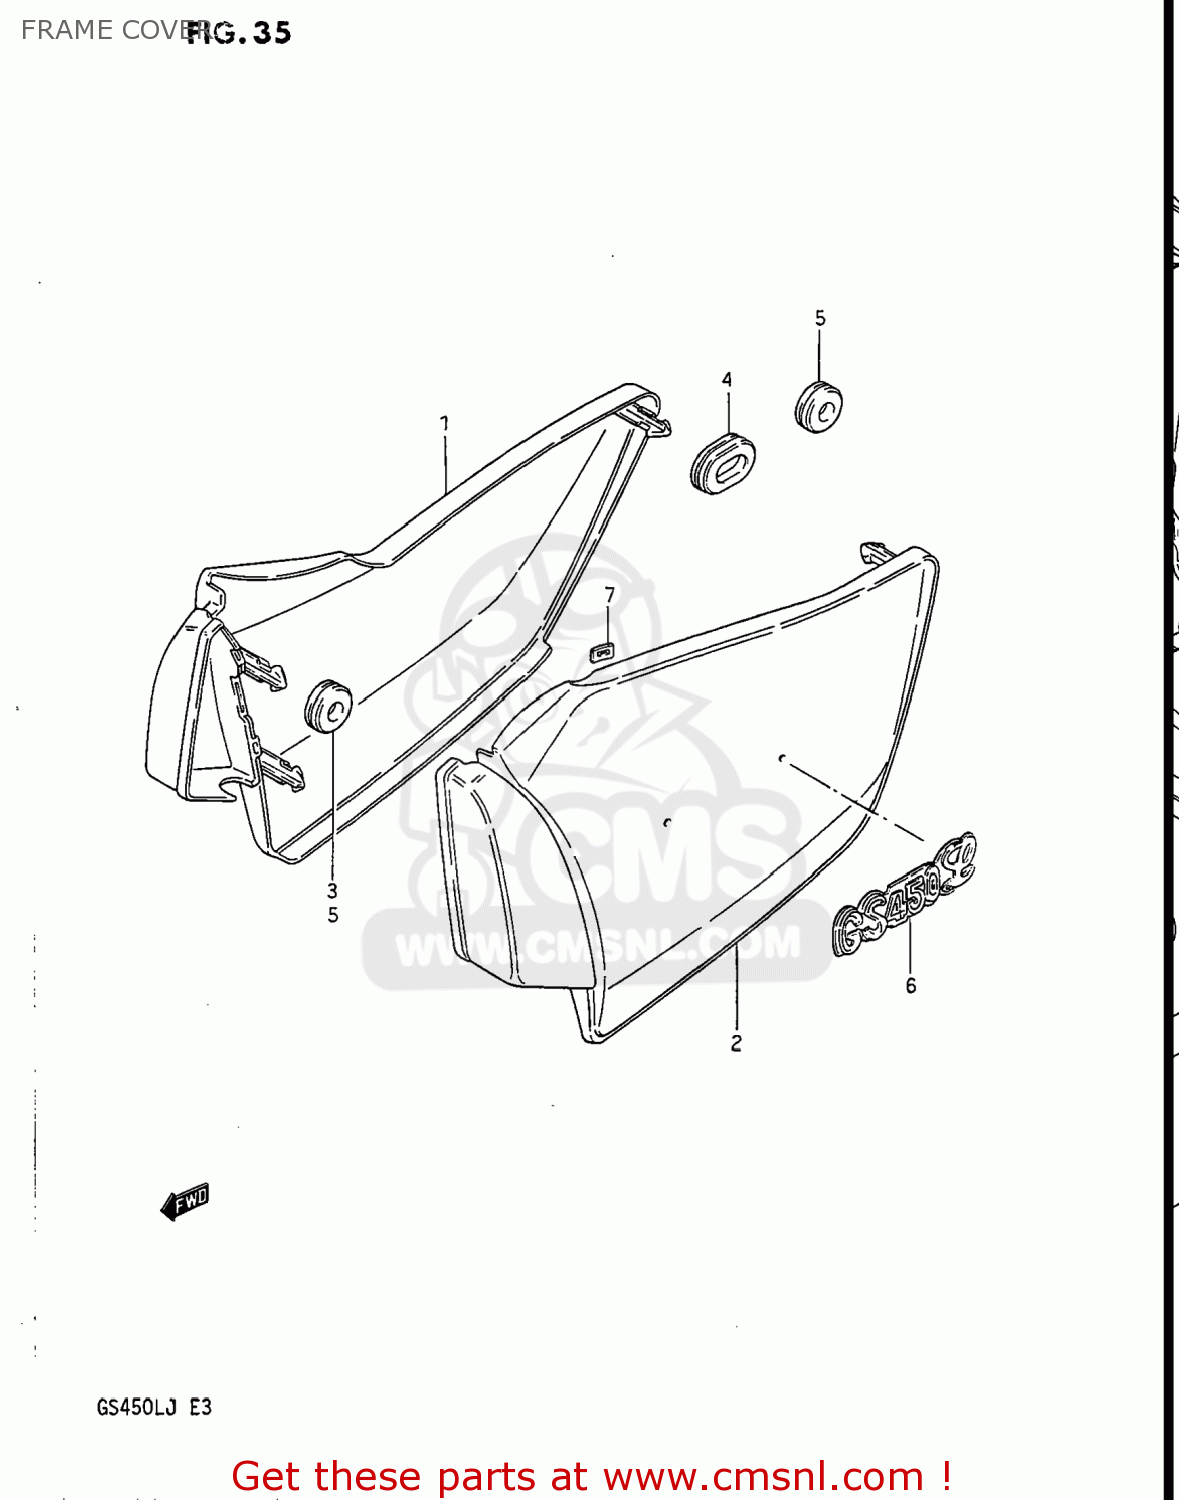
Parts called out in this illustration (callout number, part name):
1	COVER,FRAME,RIGHT
2	COVER,FRAME,LEFT
3	CUSHION
4	CUSHION
5	CUSHION
6	EMBLEM,FRAME COVER
7	NUT
